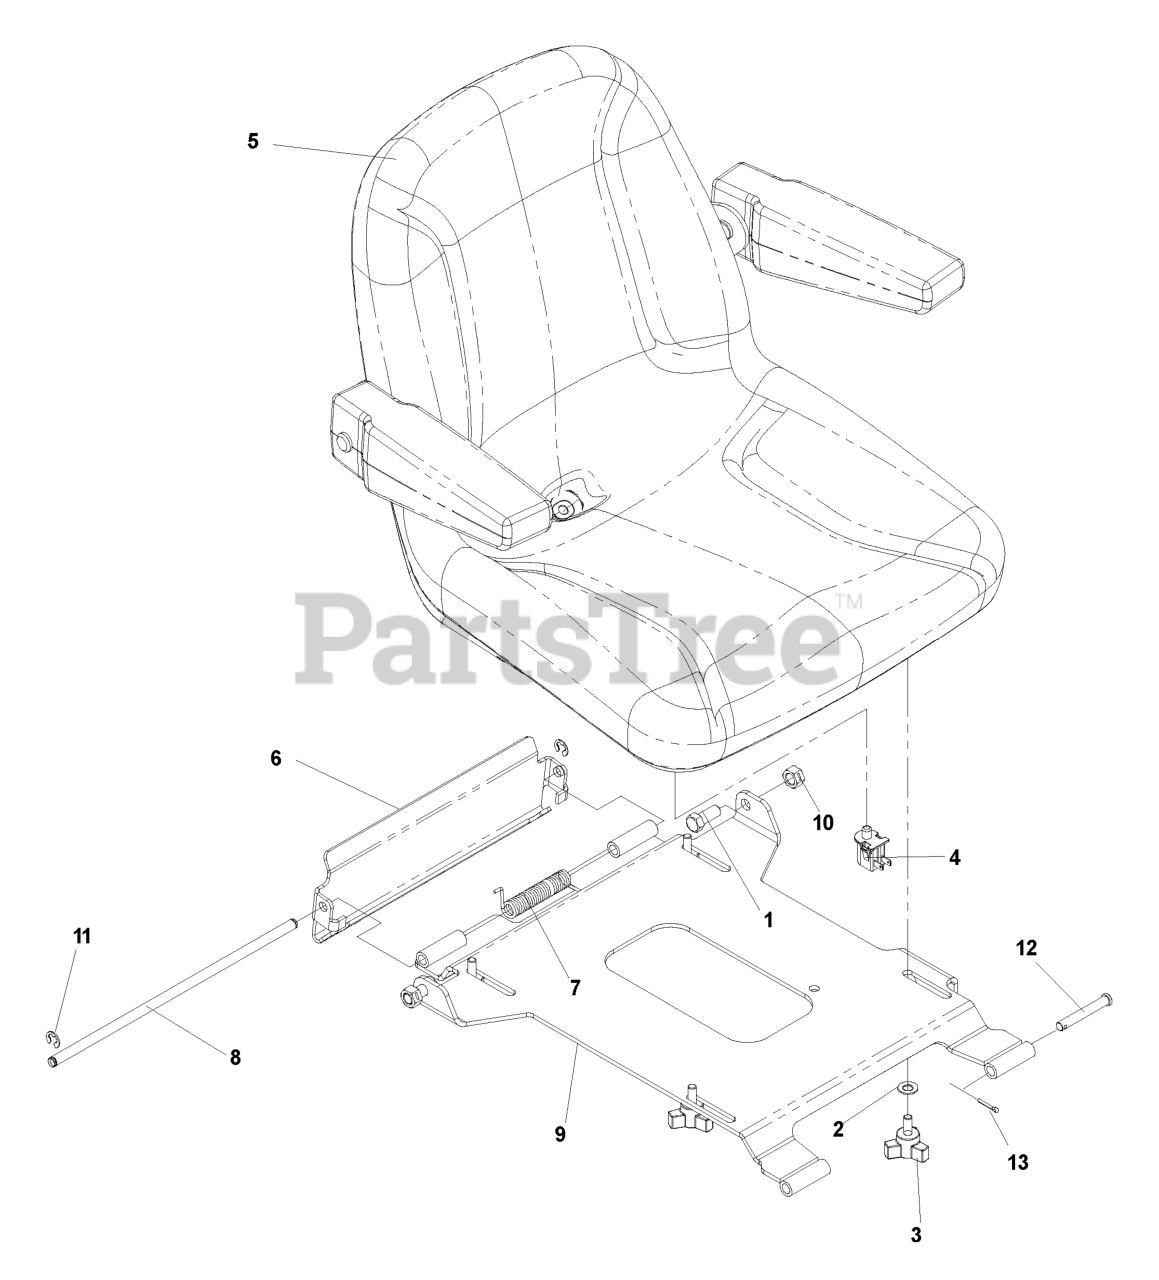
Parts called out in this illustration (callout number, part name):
1	HCS 7/16-14 X 1 GR 5 ZD
2	WASHER, 3/8 DISC SPRING SPEC
3	KNOB W/STUD
4	SEAT SWITCH
5	SEAT W/ARMRESTS
6	SEAT LATCH BRACKET
7	TORSION SPRING (SEAT)
8	SEAT LATCH ROD
9	SEAT MOUNT WLDMT, PAN
10	NUT 7/16C CENTERLOCK
11	E RING 3/8"
12	CLEVIS PIN 3/8
13	RP_COTTER PIN 1/8 X 3/4
